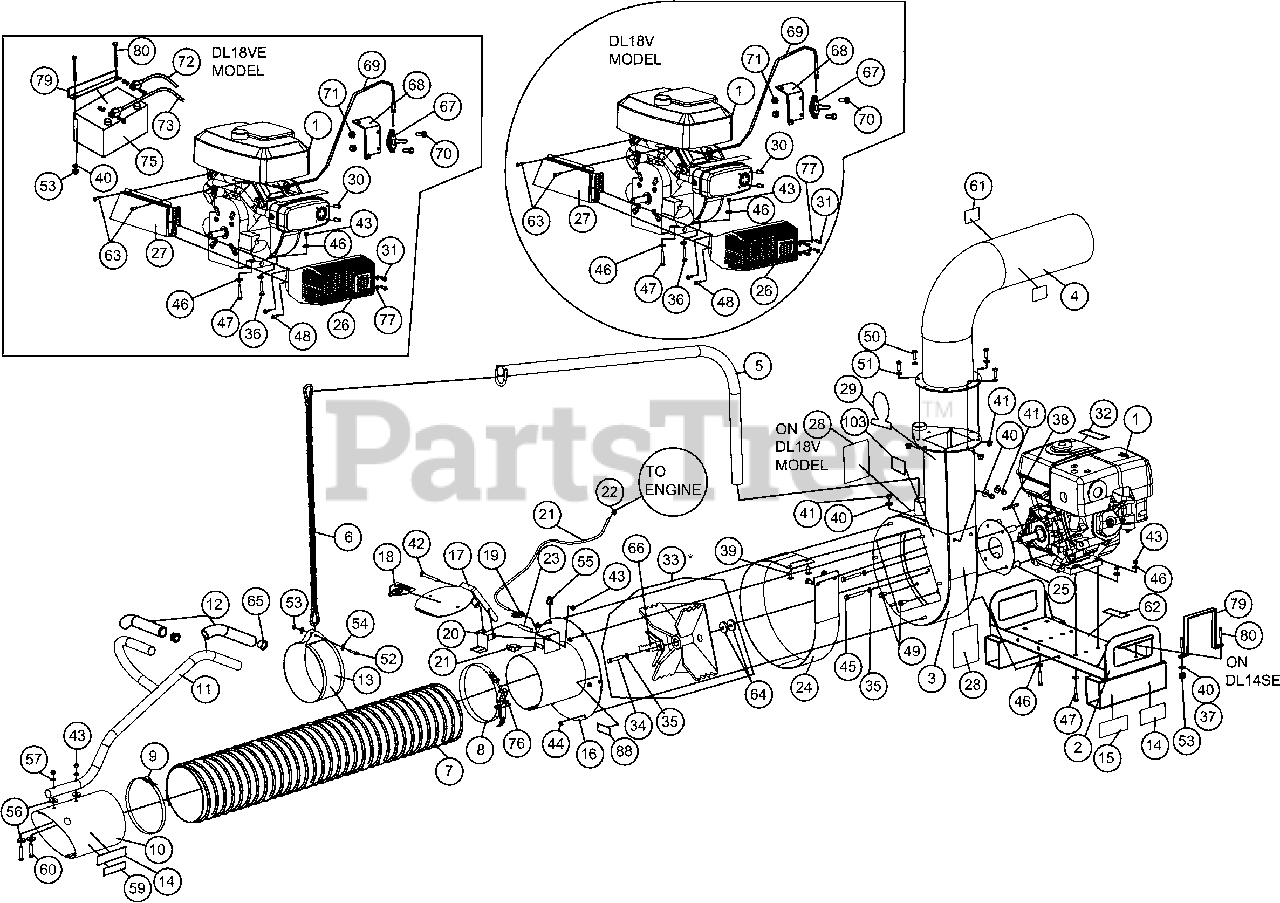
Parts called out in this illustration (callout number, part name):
1	ENGINE VANGUARD ELECTRIC
2	BASE ENGINE WA
3	HOUSING WA DL18 W/LABELS
4	ELBOW ASSY 7" DL
5	BOOM WA DL
6	CHAIN HOSE HANG DL
7	HOSE 10" X 10"
8	CLAMP QUICK RELEASE 10"
9	CLAMP HOSE 10"
10	NOZZLE 10" STEEL FORMED W/LABELS
11	HANDLE NOZZLE WA DEBRIS LOADER
12	GRIP 1 1/4 I.D. X 9.5 LONG
13	BAND HOSE BOOM 10" FORMED
14	LABEL WARNING ENGINE OVERHEAT
15	LABEL SPARK ARRESTOR
16	PLATE FRONT WA DL 10"
17	FLAPPER WA 10" W/LABELS
18	LABEL WARNING OPEI
19	STRAIN RELIEF HEYCO 1244
20	LEVER HOSE SWITCH
21	SWITCH AND HARNESS DL ASSY
22	CONNECTOR TAP IN SQUEEZE
23	SPACER 3/8" X 2 1/2"
24	LINER DL18
25	PLATE ENGINE MOUNT DL18
26	GUARD MUFFLER DL18
27	GUARD MANIFOLD DL18
28	LABEL DL INSTRUCTION/WARNING
29	LABEL LOGO DL12/13/18
30	SPACER CONTROL LIFT
31	SCREW SN #10 X 1" TYPE A SLOT HWH
32	LABEL WARNING FUEL EN/SP
34	SCREWCAP 3/8"-24 X 2 1/4" GR 8.
35	WASHER LOCK 3/8"
36	SCREWCAP 5/16-18 X 2" HCS ZP
37	WASHER 1/4" ZP
38	KEY 1/4 SQ X 2 3/4"
39	BOLT CARRIAGE 3/8 -16 X 1" ZP
40	WASHER 3/8 FLAT CUT
41	NUT LOCK 3/8-16 HEX ZP
42	BOLT CARRIAGE 5/16" - 18 X 3 1/2" ZP
43	NUT LOCK 5/16-18 HEX ZP
44	NUT FLANGE 5/16-18 HEX ZP
45	SCREWCAP 3/8-16 X 1 3/4" HCS ZP
46	WASHER 5/16 FLAT ZP
47	SCREWCAP 5/16-18 X 1 3/4" HCS ZP
48	SCREW SM 1/4 X 3/4" TYPE AB HX WF
49	HEX WASHER FACE BOLT 3/8-16 X 3/4
50	SCREWCAP 3/8-16 X 1" HCS ZP
51	WASHER 3/8 SAE
52	SCREWCAP 1/4"-20 X 2 3/4" HCS ZP
53	NUT LOCK 1/4-20 HEX ZP
54	WASHER 1/4-20 HEX ZP
55	CLAMP HOSE FUEL LINE
56	WASHER FENDER 5/16
57	WASHER 5/16 SAE
58	NOT APPLICABLE TO THIS MODEL
59	LABEL SECURE NOZZLE
60	SCREWCAP 5/16" - 18 X 2"
61	LABEL FLYING DEBRIS
62	WARNING SECURE
63	BOLT 1/4"-20 X 1/2" SER FLANGE
64	NOT APPLICABLE TO THIS MODEL
65	PLUG TUBE INSERT 1.25 OD
66	DEBRIS REDUCER DL12/13/18
67	THROTTLE CONTROL BLOWER
68	BRACKET MOUNT THROTTLE CONTROL
69	CABLE THROTTLE DL18
70	SCREW MACH FLAT HD PHIL #10-24
71	NUT LOCK #10-24 HEX
72	CABLE BATTERY RED 36"
73	CABLE BATTERY BLACK 20"
74	NOT APPLICABLE TO THIS MODEL
76	PIN SAFETY
77	WASHER LOCK 1/4" EXTERNAL TOOTH
78	TERMINAL PIGGY BACK 3/16"
79	BRACKET BATTERY DL
80	SCREWCAP 1/4"-20 X 7" HCS ZP
88	LABEL, WARNING LINER DL
103	LABEL MADE IN U.S.A.
